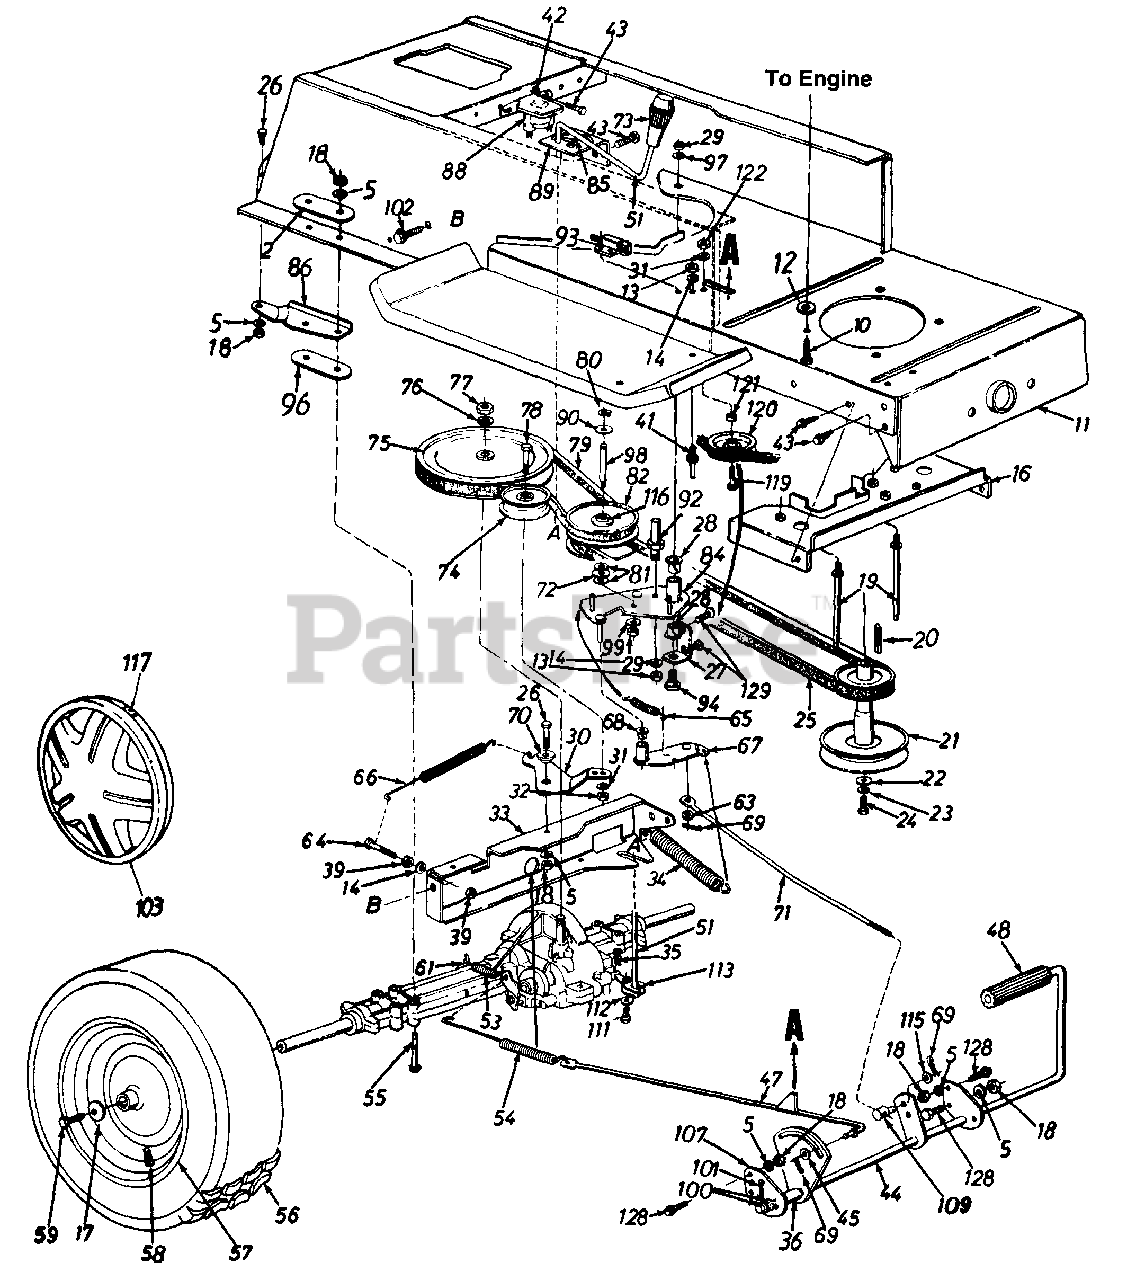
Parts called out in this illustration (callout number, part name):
5	L-Wash. 5/16" I.D.
10	Hex L-Wash. Tap Scr. 3/8-16 x 1.5" Lg. (Twin Cylinder)
13	Hex Nut 1/4-20 Thd.
14	L-Wash. 1/4" I.D.
18	Hex Nut 5/16-18 Thd.
19	Belt Guard Stud 3.6" Lg.
20	Sq. Key 1/4" x 1/4" x 2.00"
21	Engine Pulley (Twin Cylinder)
22	Fl-Wash. 7/16" I.D. x 1.25"
23	L-Wash. 7/16" I.D.
24	Hex Bolt 7/16-20 x 1.50" Lg.
25	Variable-Speed Belt
26	Hex Bolt 5/16-18 x .75" Lg.
27	Bearing Shaft Bracket Ass'y.
28	Flanged Nyliner Brg. 5/8" I.D. x .88" Lg.
29	Hex Nut 3/8-24 Thd.
31	L-Wash. 3/8" I.D."
32	Hex Nut 3/8-24 Thd.
35	inter. Cotter Pin
36	Spacer .63" I.D.
39	Hex Nut 1/4-28 Thd.
41	Belt Guard Pin
42	Ext. L-Wash. 1/4" I.D.
43	Hex Wash. Hd. S-Tap Scr. 1/4-20 x .50" Lg.
47	Brake Rod Ass'y.
48	Foot Pad
51	Shift Lever Ass'y.
53	Ext. Spring .38" O.D. x 2.5"
54	Ext. Spring .59" O.D. x 7.08"
55	Hex Bolt 5/16-18 x 3.5" Lg.
56	Wheel Ass'y. Comp.
57	Wheel Rim Only
58	Air Valve
59	Hex Bolt 5/16-24 x .75" Lg.
61	Brake Return Spring Anchor
63	Fl-Wash .34" I.D. x .68" O.D.
64	Hex Bolt 1/4-28 x 1.25" Lg.
65	Ext. Spring
66	Ext. Spring .62" O.D x 6.12"
68	Flanged Bearing
69	Cotter Pin 3/32" Dia.
70	Shoulder Spacer .27" Lg.
71	Speed Control Link
72	Truss Bearing .56 Dia. x 1.25"
73	Shift Knob
74	Fl-Idler Pulley 3.25" x .75"
75	"V" Pulley
76	Bell-Wash. 56" I.D. x 1.125"
77	Hex Jam Nut 5/16-18 Thd.
78	Hex Bolt 3/8-24 x 1.75" Lg.
79	Variable Speed Belt
80	Snap Ring .56" Dia,
81	Fl-Wash
82	Variable Speed Pulley Ass'y. 5" O.D.
90	Teflon Washer 565" I.D.
92	Belt Keeper 3" Lg.
93	Safety Switch (Clutch)
94	Shld. Bolt 3/8-24 x 3.12" Lg.
96	Transaxle Spacer
97	Bell-Wash .38" I.D. x .88"
98	Shaft .56" Dia. x 3.875" Lg.
99	Bell-Wash .39" 1.0. x 1.12"
100	Fl-Wash .64" I.D. x .94"
101	Cotter Pin 1/8" Dia. x 1.25"
102	Hex Wash. Hd. Scr. 5/16-18 x .62" Lg.
103	Hub Cap (Gray)
111	Hex Bolt 1/4-28 x .50" Lg.
112	Bell-Wash .265" I.D. x .75"
113	Shift Lever Link Ass'y.
115	Fl-Wash .385" I.D. x .62"
116	Needle Brgs.
117	Spring Clip
119	Hex Bolt 3/8-16 x 1.25" Lg.
120	Fl-Idler w/Flanges 2.75" O.D.
121	Fl-Wash .39" I.D. x 1.12" O.D.
122	Hex Nut 3/8-16 Thd.
128	Hex Wash. TT-Tap Scr. 5/16-18 x .75" Lg.
129	Hex Wash. AB-Tap Scr. 5/16-18 x .75" Lg.
